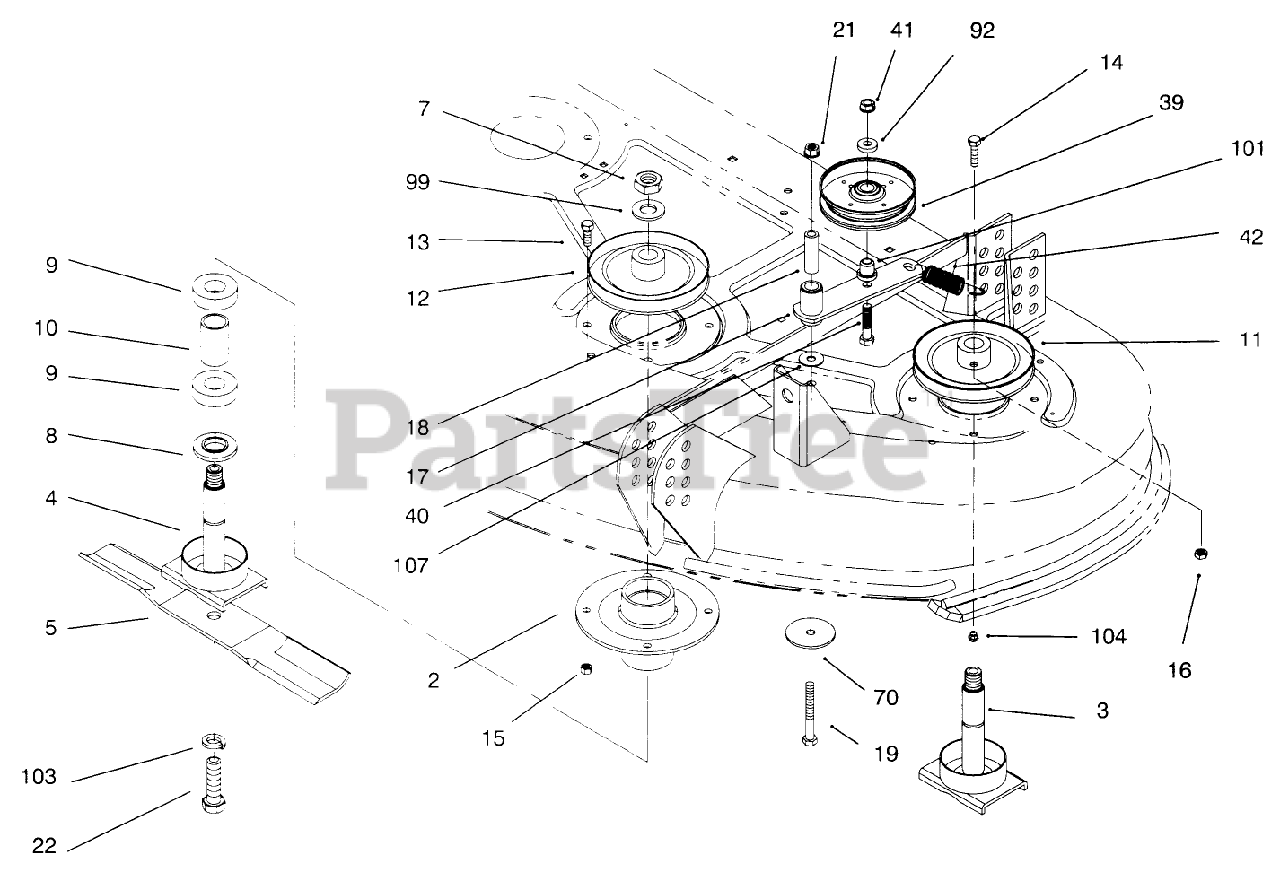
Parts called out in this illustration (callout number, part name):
2	HOUSING-SPINDLE
3	Shaft
4	SHAFT-SPINDLE
5	Blade-Recycler
7	NUT-HEX
8	SPACER-SPINDLE
9	Bearing
10	SPACER-BEARING
11	PULLEY-DECK
12	PULLEY
13	SCREW-HH
14	SCREW-HH
15	NUT-LOCK, CONE
16	NUT-JAM
17	IDLER ARM ASM
18	SPACER
19	SCREW-HH
21	NUT-HF
22	SCREW-BLADE
39	PULLEY-IDLER
40	SCREW-HH
41	NUT-HEX
42	Spring-Extension
70	WASHER-END
92	WASHER-FLAT
99	WASHER
101	BUSHING-PULLEY
103	WASHER-LOCK
104	FITTING-GREASE
107	WASHER
